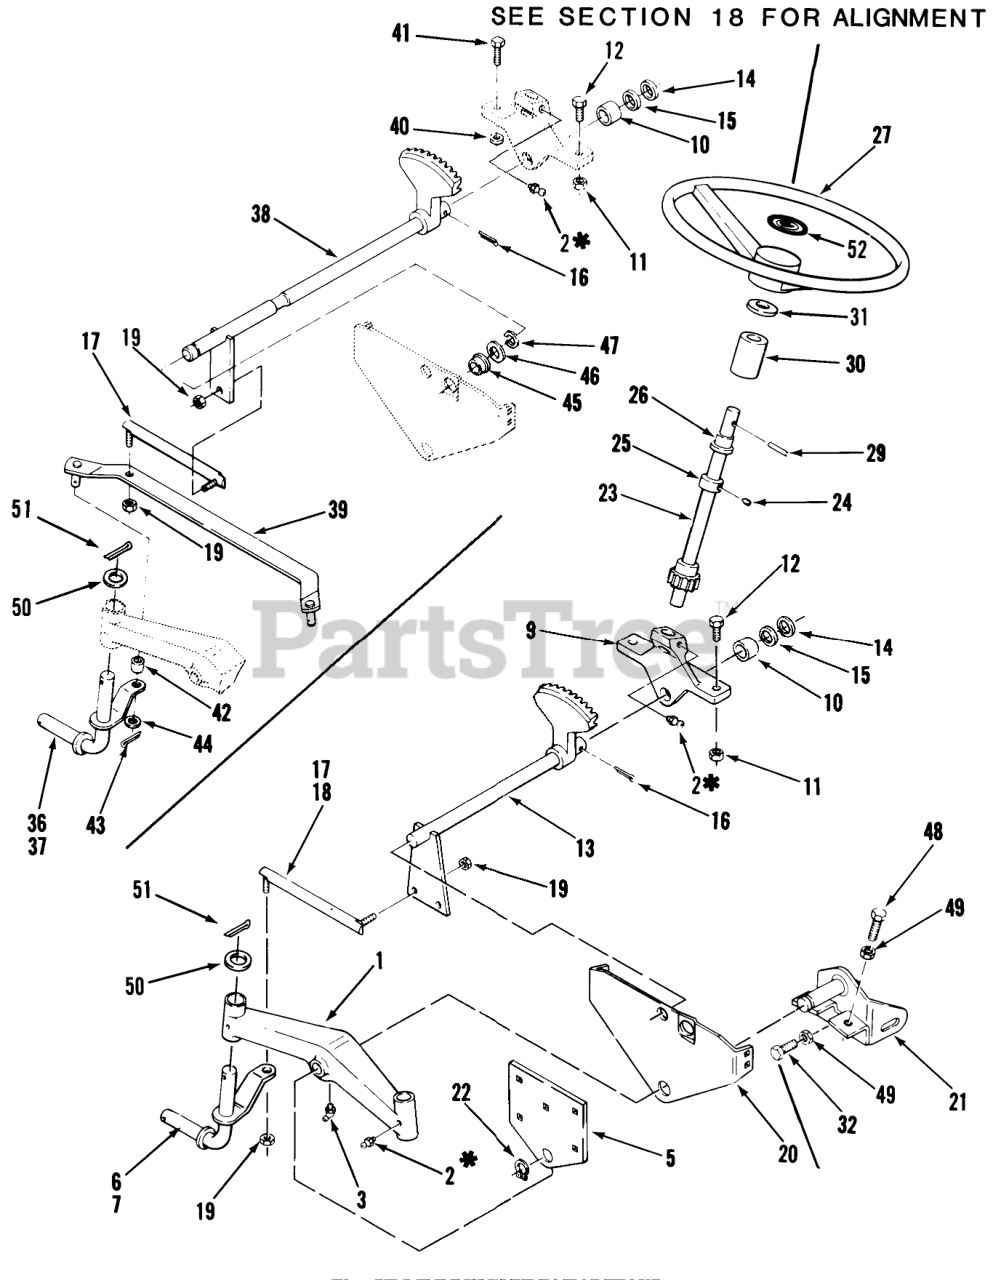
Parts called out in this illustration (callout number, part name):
1	AXLE-FRONT R
2	Zerk
3	FITTING-GREASE
5	PLATE-FRONT AXLE R
6	Front Spindle Assy RH
7	Front Spindle Assy LH
9	Support
10	BEARING-BRONZE
11	Nut
12	BOLT
13	ASSY-STRG SHFT LO R
14	WASHER-SHIM
15	WASHER
16	PIN-4
17	25LL JOINT ASSY R R
18	BALL JOINT ASSY L R
19	NUT-6
20	Support Front Axle
21	ASSY-FRONT HANGER R
22	Snap Ring
23	ASSY-STEER SHFT U R
23	ASSY-STRG SHFT-UP R
24	SCREW-SET
25	Collar
26	BEARING-FLANGED
27	STEERING WH 13" PLAS
29	Pin-Roll
30	Collar 208-3 Only
31	WASHER-FLAT
32	SCREW-HH
36	Front Spindle Assy RH 216-5 Only
37	Front Spindle Assy LH 216-5 Only
38	Assy Strg Lower B-165 Only
39	ASSY-TIE ROD R
40	WASHER
41	Bolt
42	SPACER
44	WASHER
45	BUSHING
46	WASHER SPECIAL
47	Ring
48	Bolt
49	Nut
50	WASHER
51	COTTER PIN-4
52	STEERING WHEEL INSE
